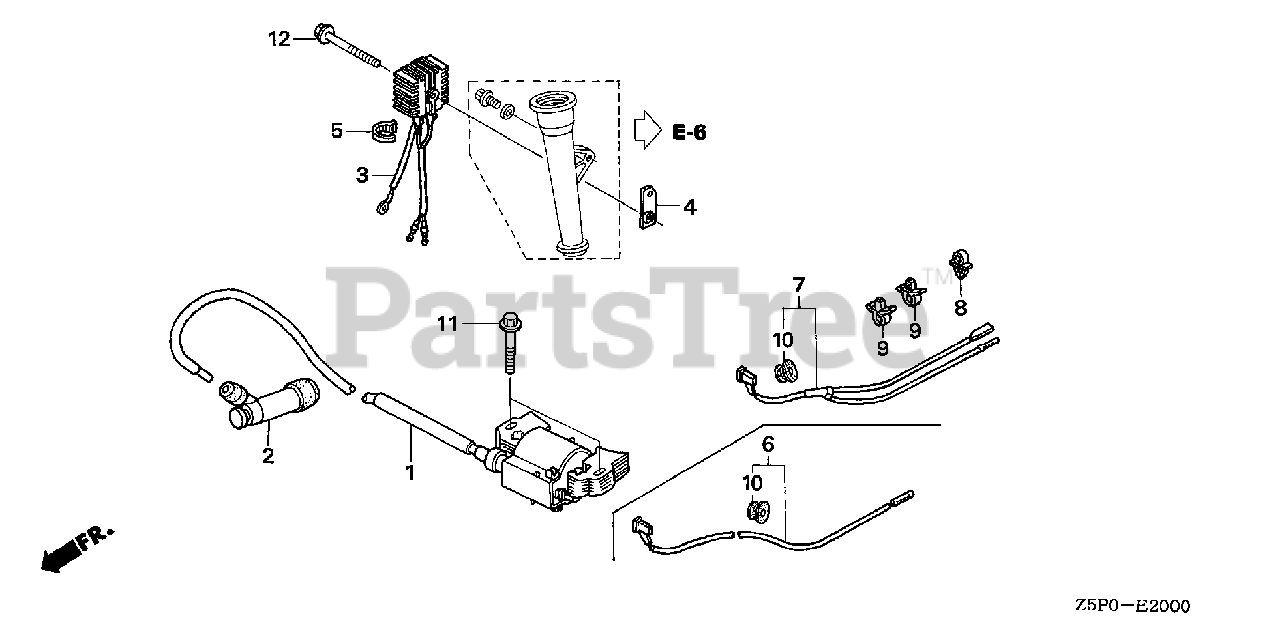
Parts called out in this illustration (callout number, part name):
1	COIL ASSY., IGNITION
2	CAP ASSY., NOISE SUPPRESSOR
3	RECTIFIER ASSY., SILICON
4	BRACKET, RECTIFIER
5	BAND B1, WIRE
7	WIRE, STOP SWITCH
9	CLIP, BRAKE PIPE (A)
10	GROMMET, WIRE CORD
11	BOLT, FLANGE (6X28) (CT200)
12	BOLT, FLANGE (6X32)
